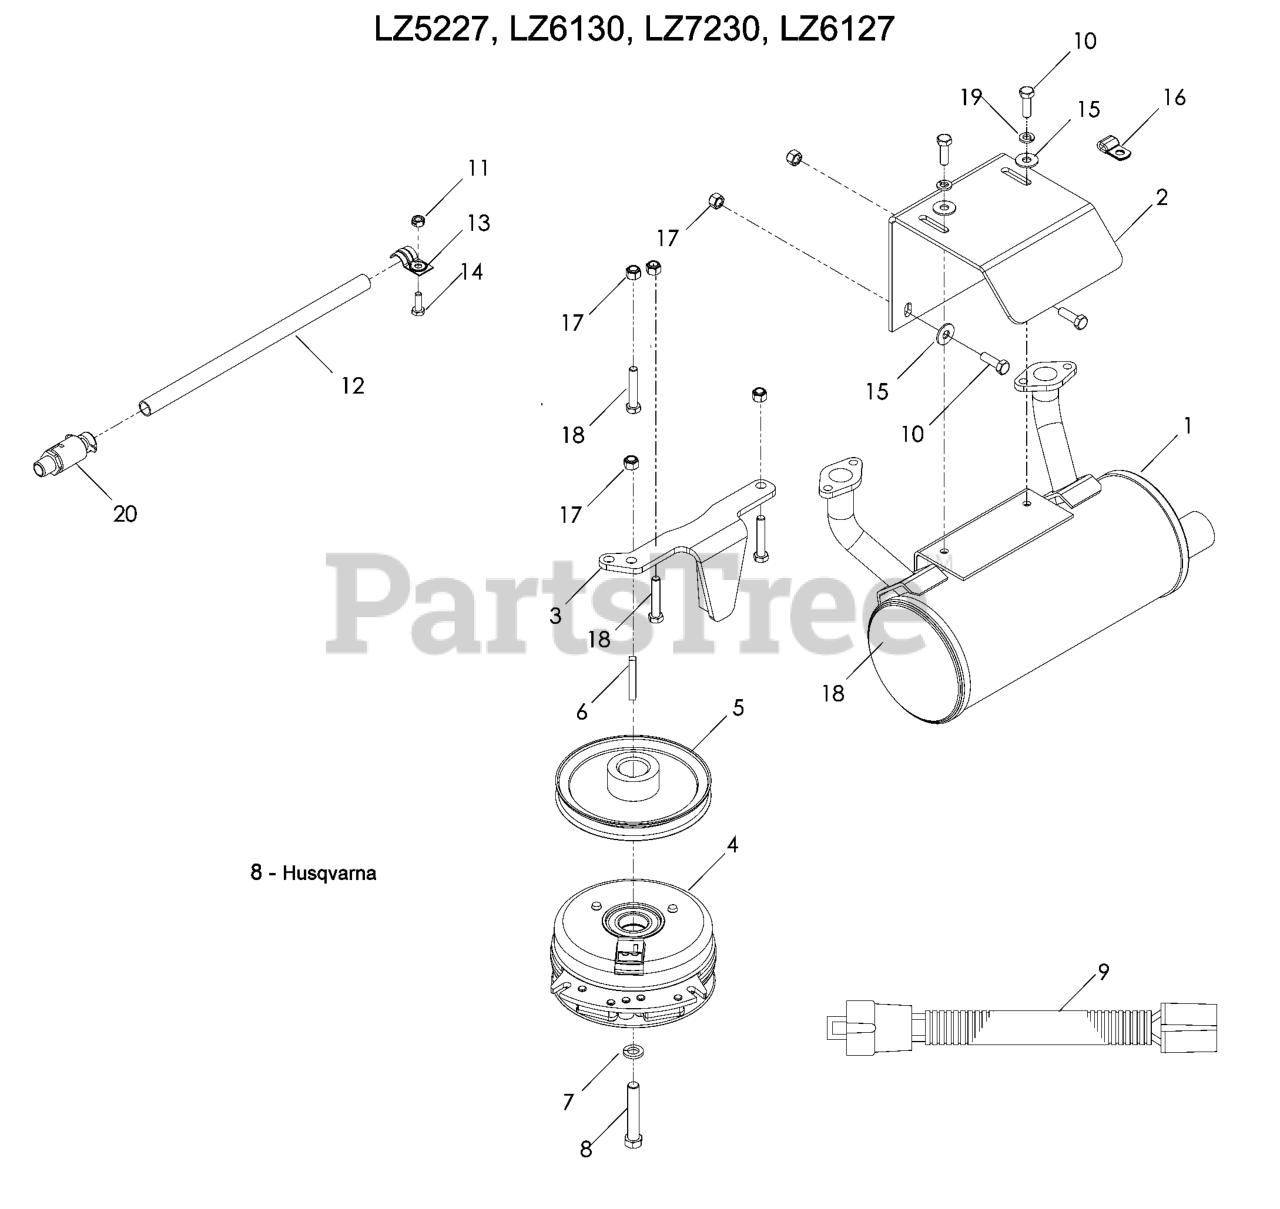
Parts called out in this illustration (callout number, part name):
1	MUFFLER KOHLER GEN II
2	MUFFLER BRACKET BLACK
3	WLDT, CLUTCH TIE DOWN BLK
4	ELECTRIC CLUTCH W/CABLE
6	KEY 1/4" SQ X 1 7/8"
7	WASHER 7/16 LOCK
8	BOLT 7/16F X 2 1/2
9	KOH PIGTAIL
10	HCS 5/16C X 1
11	NUT 1/4C CENTER LOCK
12	OIL DRAIN HOSE
14	HCS 1/4C X 3/4 HCS
15	WASHER 5/16 FLAT
16	DOUBLE TUBE CLAMP
17	NUT 5/16 NYLOC
18	HCS 5/16C X 1 3/4
19	WASHER.LOCK.HVY.HLCL.SPR.5/16
20	OIL DRAIN FITTING
